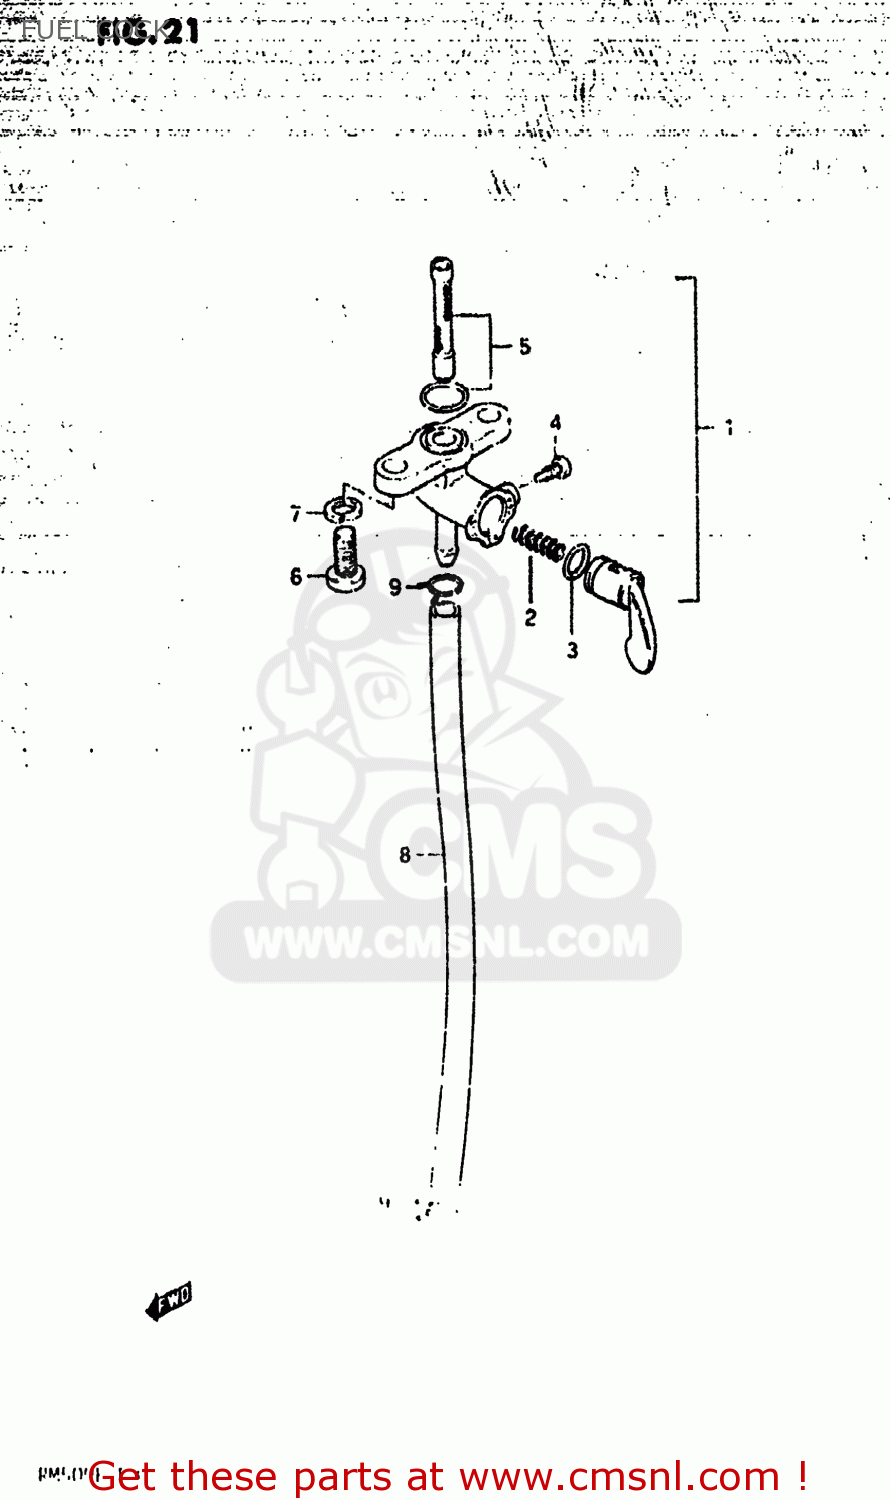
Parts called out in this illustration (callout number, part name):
1	COCK ASSY,FUEL
2	SPRING,FUEL COCK VALUE
3	O RING,LEVER
4	SCREW
5	FILTER SET FUEL
6	SCREW
7	LOCK WASHER
8	HOSE,FUEL
9	CLIP
